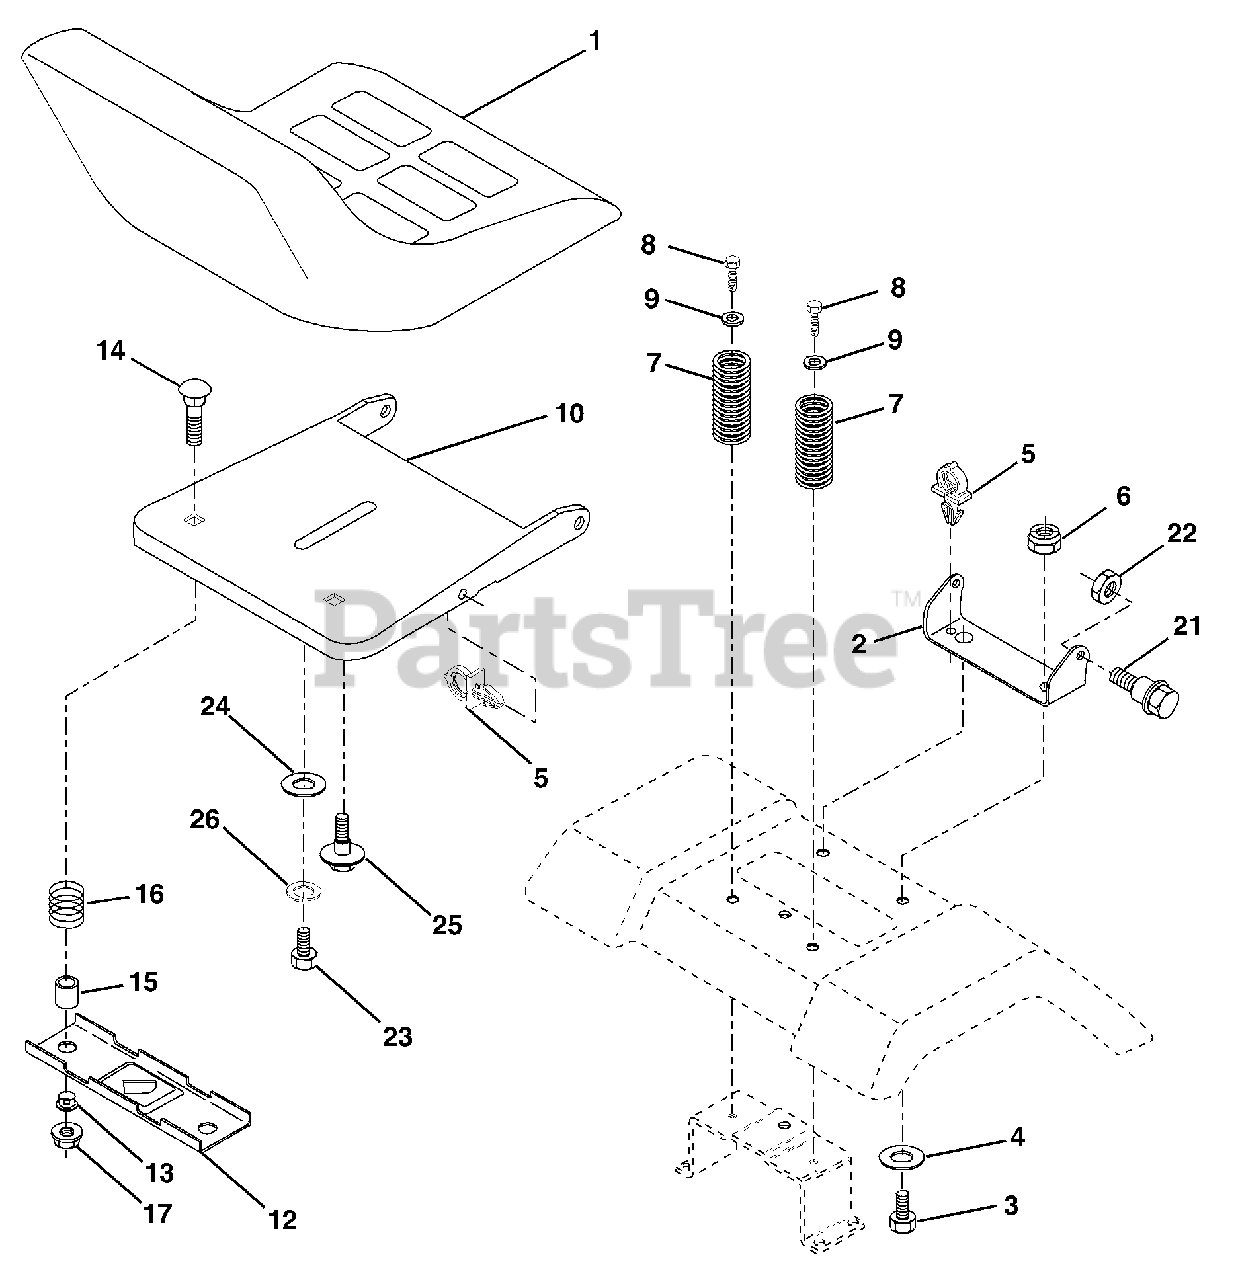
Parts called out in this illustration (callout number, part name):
1	Seat
2	Bracket Pivot Seat 8 720
3	Bolt Fin Hex 3/8-16unc X 1
4	Washer 13/32 X 1 X 10 Ga
5	Clip Push-In
6	Nut Hex w/Ins. 3/8-16 Unc
7	Spring Seat Cprsn 2 250 Blk Zi
8	Screw 3/8-16 X 1
9	Washer 13/32 X 1 X 14 Ga.
10	Pan Seat
12	Bracket Mounting Switch
13	Bushing Snap Blk Nyl 50 Id
14	Bolt Rdhd Sqnk 1/4-20x1-1/2
15	Spacer Split 28x 96 Yel Zinc
16	Spring Cprsn 1 27 Blk Pnt
17	Nut Lock 1/4 Lge Flg Gr 5 Zinc
21	Bolt Shoulder 5/16-18 Unc-2A
22	Nut Hex Lock W/Ins 5/16-18
23	Bolt, Hex Black
24	Washer 17/32 X 1-3/16 X 12 Ga.
25	Bolt Shoulder 5/16-18 X 62
26	Washer Lock
